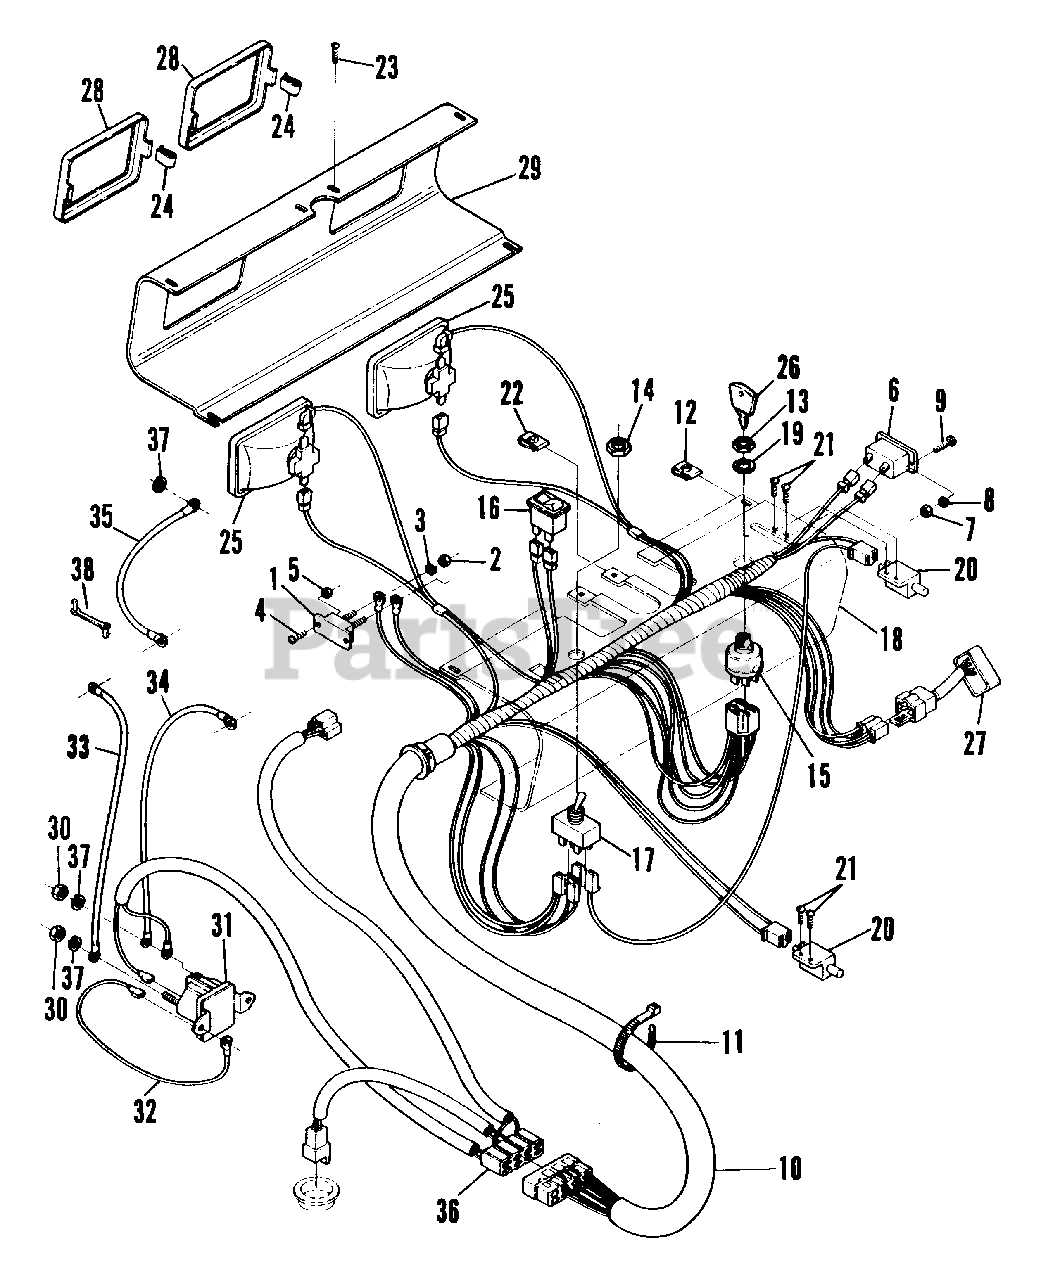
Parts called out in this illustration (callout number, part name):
1	CIRCUIT BREAKER
2	NUT, #10-32
3	LOCKWASHER, #10,Internal Tooth
4	MACHINE SCREW, #10-24 x 1/2
5	NUT, Keps, #10-24
6	HOURMETER, LT
7	NUT, MS #6-32
8	WASHER, #6, Internal Tooth
9	MACHINE SCREW, #6 C x 1/2, Round Head
10	HARNESS WIRING
11	CABLE TIE
12	CLIP NUT
13	NUT, 5/8"-32
14	NUT, 1/2"-27, HT
15	KEY SWITCH
16	SWITCH-ROCKER SPST
17	TOGGLE SWITCH
18	PANEL, Rear
19	WASHER, 5/8", Internal Tooth
20	SWITCH
21	SCREW, #12-14 x 1/2, Hex Flat Head, Self-Tapping
22	CLIP NUT
23	SCREW, #10-24 x 1/2" Hex Washer Self-Tap (Torx)
24	CLIP, Headlight
25	LIGHT, Head
26	KEY, Switch (With Cover)
28	MOUNTING BEZEL
29	PANEL, Front
30	NUT, 1/4" Hex C
31	SOLENOID
32	CABLE, Solenoid 6" (14 HP Kohler/18 HP Kohler)
33	CABLE, 28" (14 HP Kohler)
34	CABLE, 13" (14 HP Kohler/18 HP Kohler)
35	CABLE, 23" (14 HP Kohler/18 HP Kohler)
36	HARNESS (14 HP Kohler)
37	WASHER, 1/4" Int. Tooth Lock
38	WIRE TIE (14 HP Kohler)
